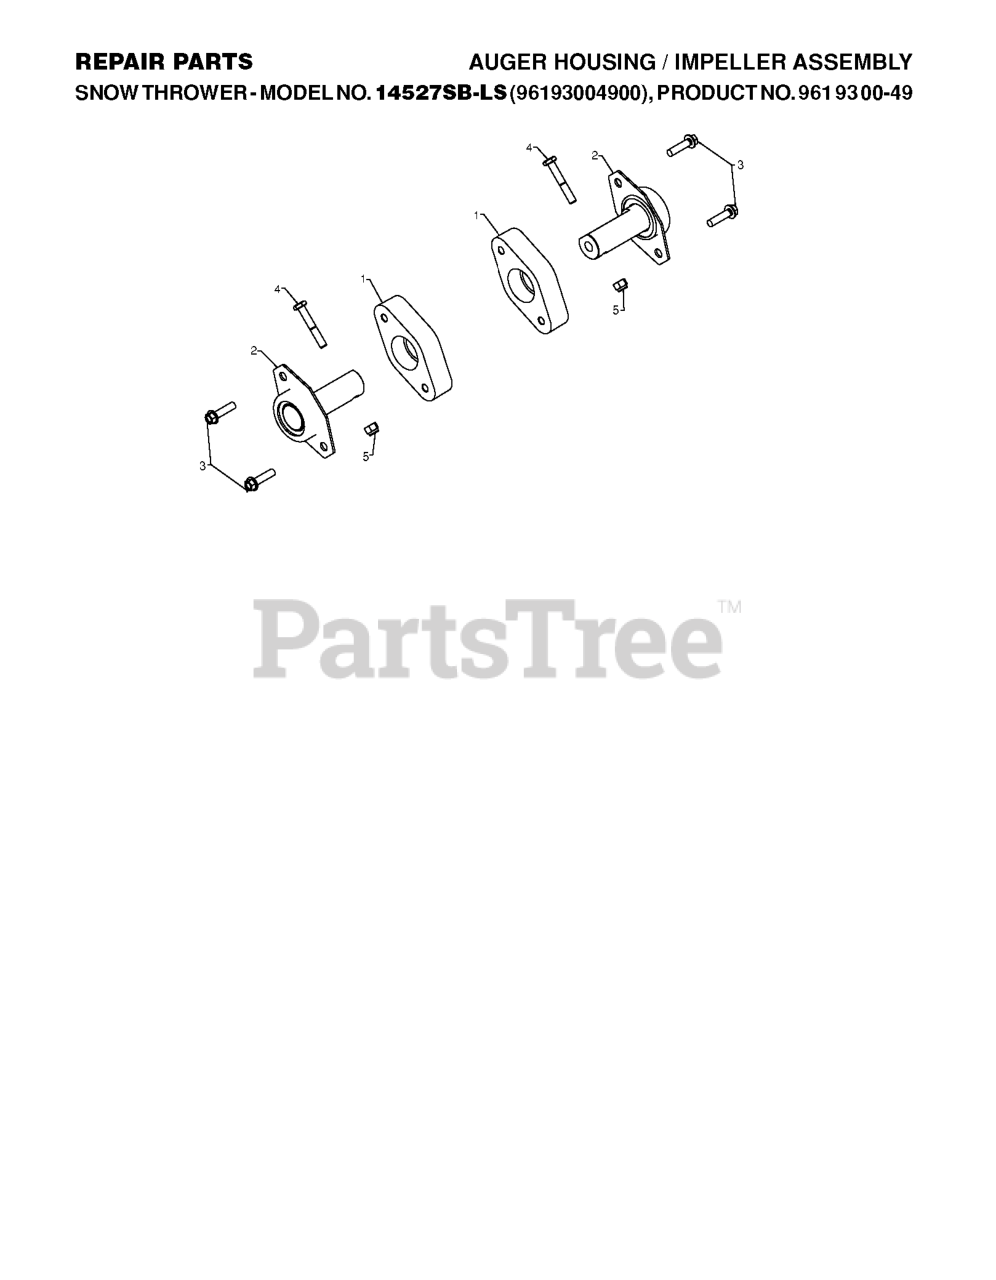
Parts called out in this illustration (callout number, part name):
1	RETAINER.PLASTIC
2	BEARING.BALL.AUGER.FLAT.
3	SCREW, HEX HD 5/16X1
4	SCREW.HEX.HD1/4-20X
5	LOCKNUT.NYLOC.1/4-20
